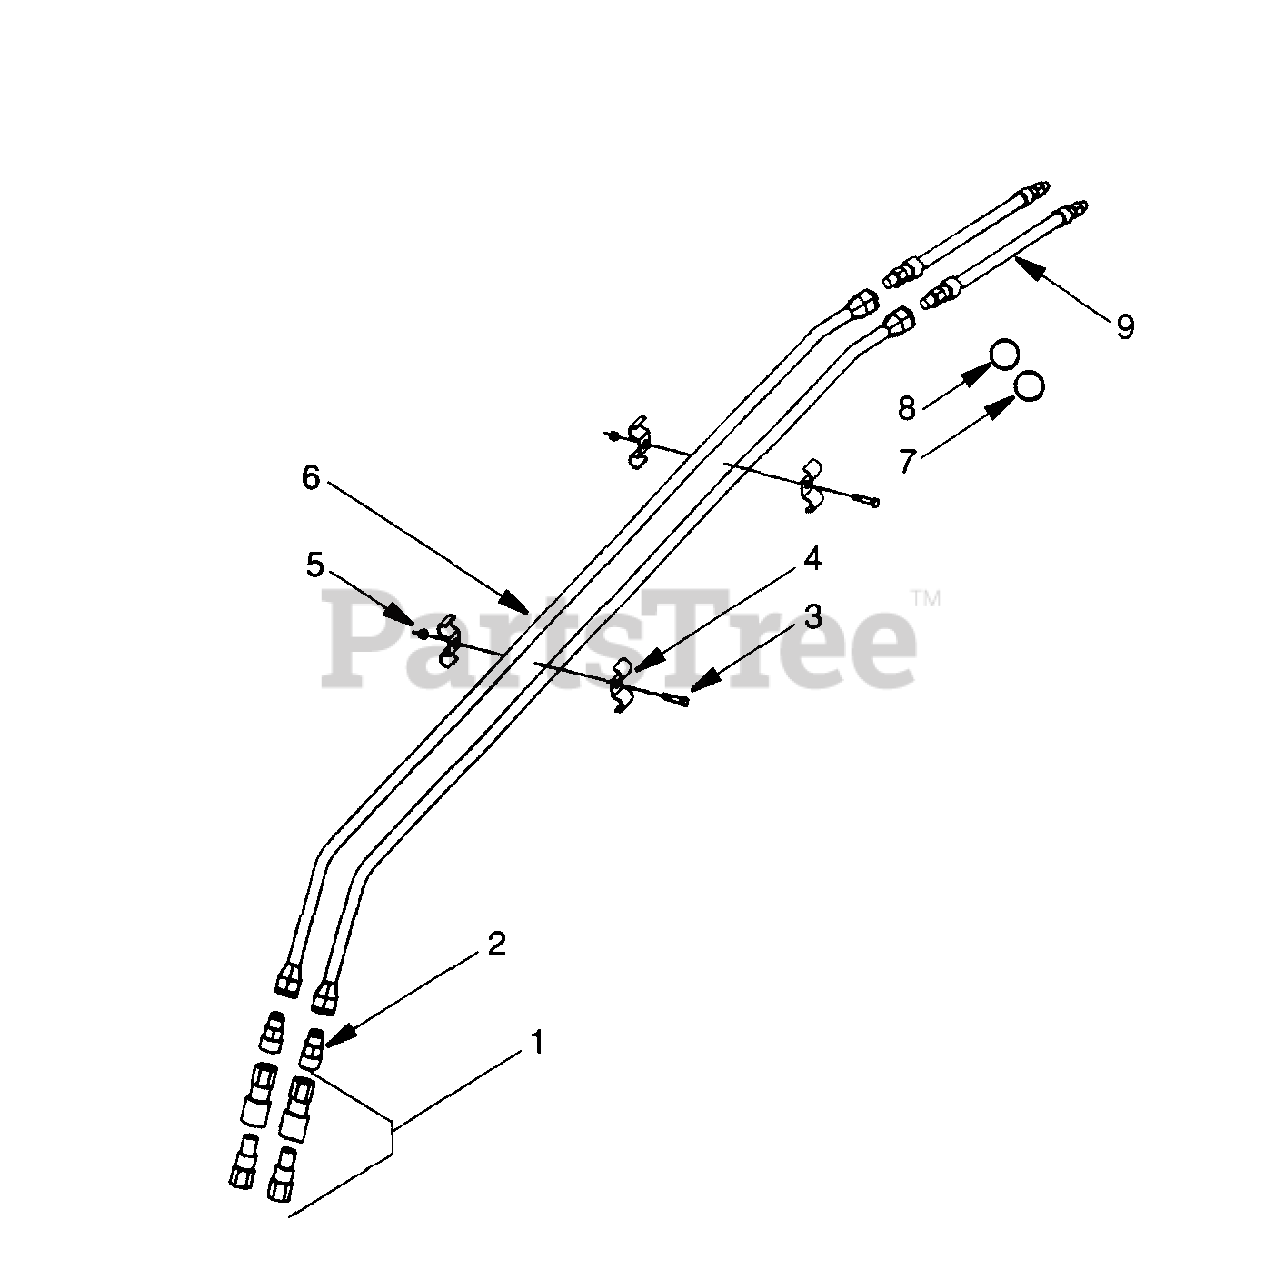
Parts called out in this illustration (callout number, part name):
1	Hydraulic Quick Coupler Set
2	Adapter, 3/4 JICM x 3/8 JICM
3	Hex Cap Screw, GR5 5/16 x 3/4
5	Locknut, 5/16
6	Auxiliary Feedline
7	Yellow Spiral Band
8	Green Spiral Band
9	Hose, 3/8-54", 3/8 NPT x 3/4 JICM
